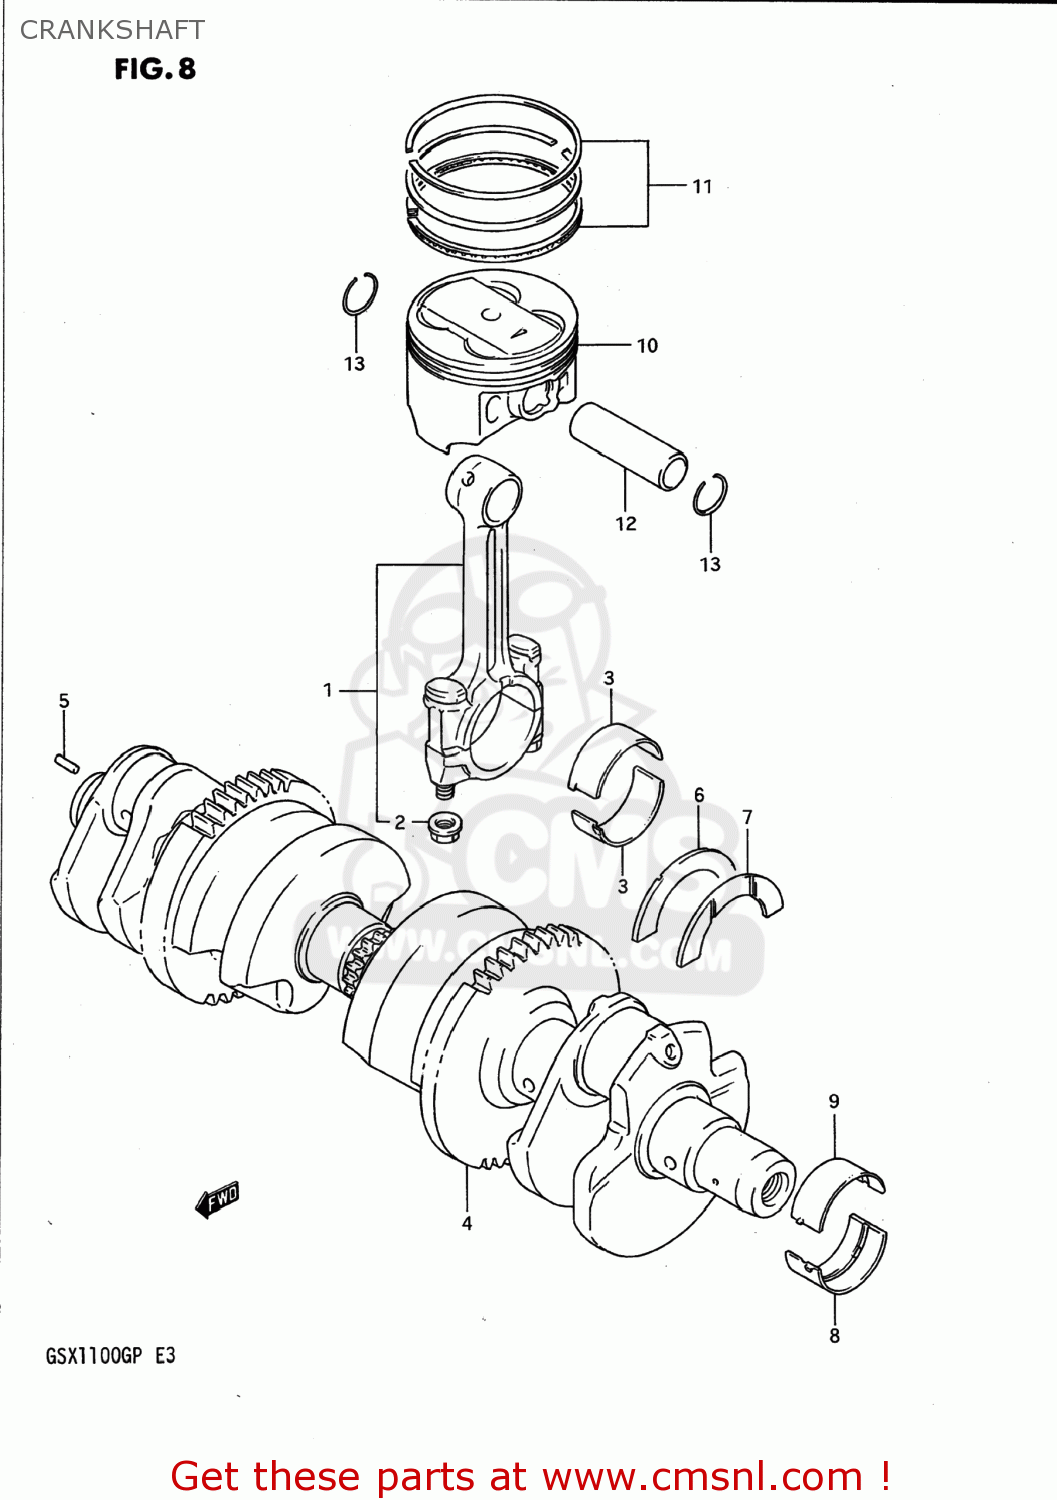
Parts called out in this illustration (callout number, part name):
1	ROD ASSEMBLY,CONNECTING
2	NUT
3	BEARING,CRANK PIN
4	CRANKSHAFT SET
5	PIN
6	BEARING,CRANK THRUST(GREEN)
7	BEARING,CRANK THRUST(RED)
8	BEARING,CRANKSHAFT LWR
9	BEARING,CRANKSHAFT UPR
10	PISTON
11	RING SET,PISTON
12	PIN,PISTON
13	CIRCLIP,PISTON PIN
